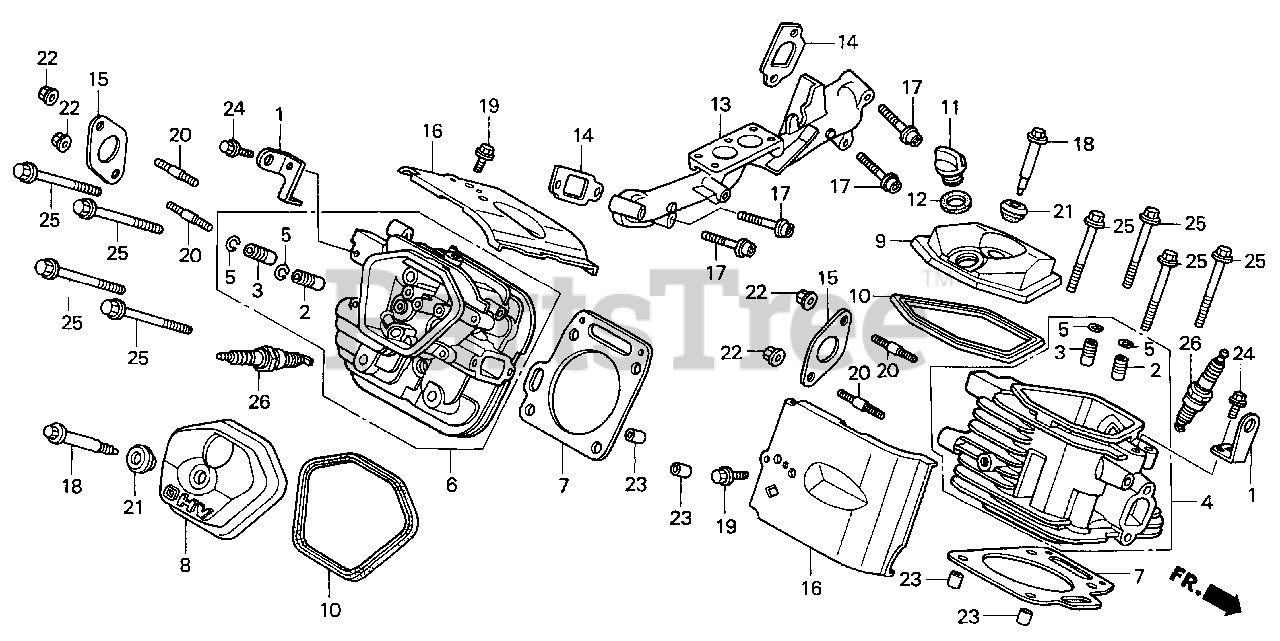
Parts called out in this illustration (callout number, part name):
1	HANGER, ENGINE
2	GUIDE, VALVE (OS)
3	GUIDE, EX. VALVE (OS)
4	CYLINDER HEAD (#1)
5	CLIP, VALVE GUIDE
6	CYLINDER HEAD (#2)
7	GASKET, CYLINDER HEAD
8	COVER, HEAD
9	COVER, HEAD FILLER
10	GASKET, CYLINDER HEAD COVER
11	CAP, OIL FILLER
12	GASKET, OIL FILLER CAP
13	MANIFOLD, IN.
14	GASKET, IN. MANIFOLD
15	GASKET, EX. PIPE
15	GASKET, EX. PIPE (WACKER)
16	SHROUD, HEAD
17	BOLT, SOCKET (8X45)
18	BOLT, HEAD COVER
19	BOLT, FLANGE (6X14)
20	BOLT, STUD (8X22)
21	WASHER, HEAD COVER
22	NUT, FLANGE (8MM)
23	PIN A, DOWEL (12X20)
24	BOLT, FLANGE (8X20)
25	BOLT, FLANGE (10X80)
26	SPARK PLUG (BPR2ES) (NGK)
26	SPARK PLUG (J14CR-U)
26	SPARK PLUG (ZGR4A) (NGK)
26	SPARK PLUG (J16CR-U)
26	SPARK PLUG (ZGR5A) (NGK)
